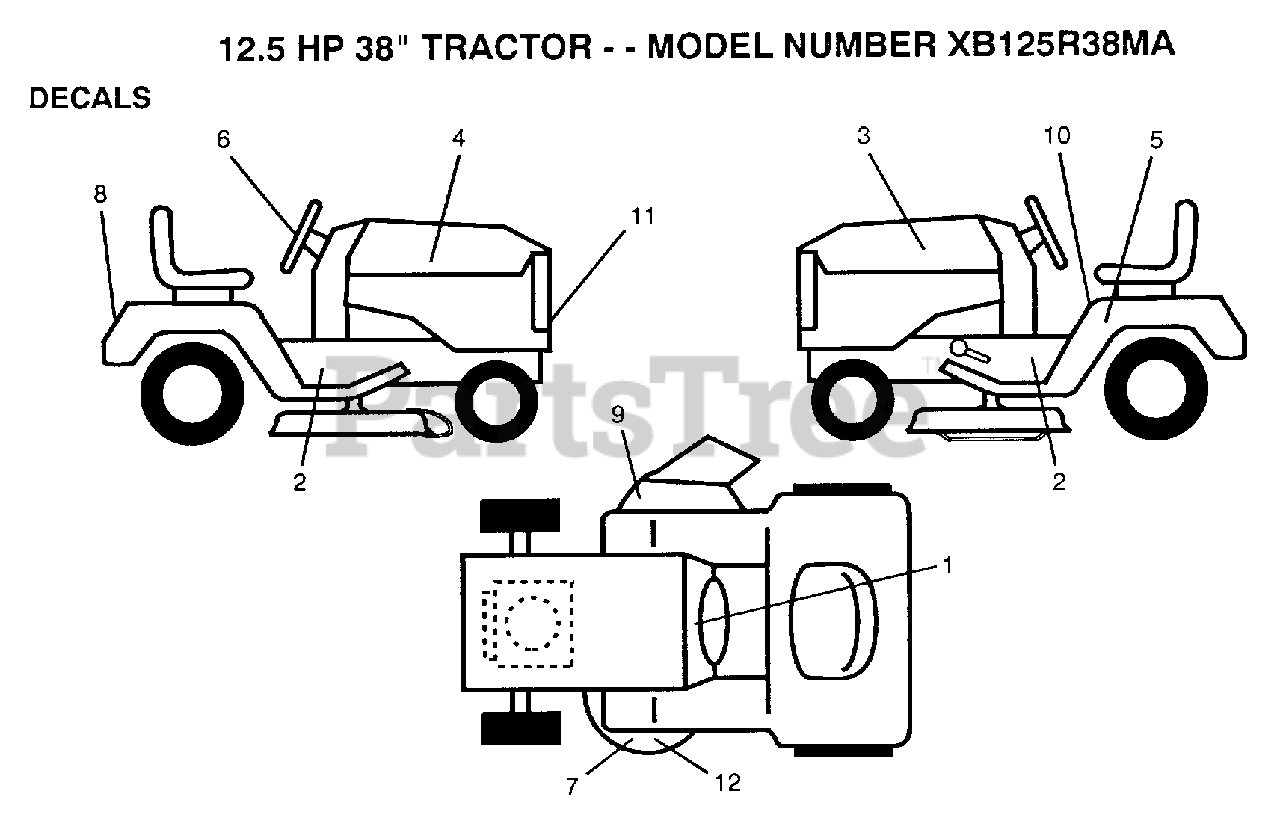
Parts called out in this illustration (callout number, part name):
2	DECAL, SPEED/DECK SIZE, CHASSIS
3	DECAL HOOD LH
4	"DECAL,HOOD RH "
5	IND HGT DECK DECA
6	"DECAL,STR WHL "
7	DECAL YT
8	DECAL, FENDER
9	DECAL WARNING
10	DECAL CAUTION
11	"DECAL,GRILL "
12	"DECAL,ENVIRO DECK"
